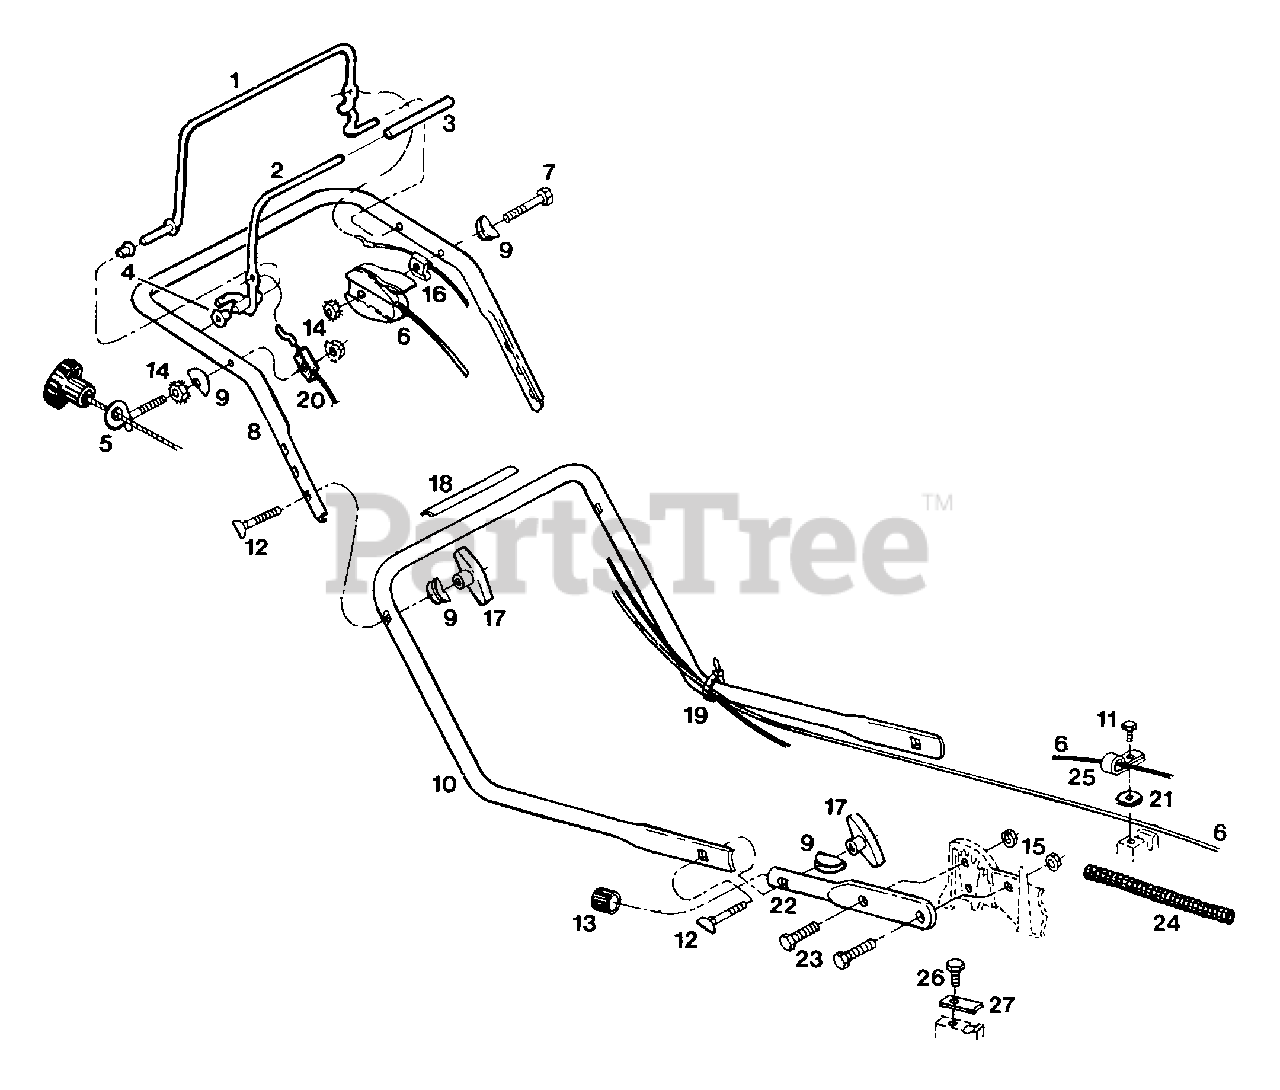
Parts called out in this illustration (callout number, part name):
1	BAIL - engine control
2	BAIL - traction
3	SLEEVE - traction bail
4	BUSHING - traction bail
5	GUIDE - rope
6	CONTROL - Throttle
7	BOLT - Hex (1/4-20 x 2 1/2")
8	HANDLE - Upper
9	WASHER - curved
10	HANDLE - Lower
11	SCREW - Hex tap (1/4-20 x 5/8")
12	BOLT - curved head (5/16-18 x 2 1/4")
13	PLUG - Cap
14	NUT - Hex (1/4-20) keps
15	NUT - Hex flange (5/16-18)
16	CABLE - engine/blade
17	KNOB - Handle
18	DECAL - control bail
19	CABLE - Tie
20	CABLE - Traction
21	WASHER - Plain
22	STUB - Handle mtg
23	BOLT - Hex (5/16-18 x 1")
24	COVER - Cable
25	CLAMP - cable
26	SCREW - hex 1/4 20 x 1/2
